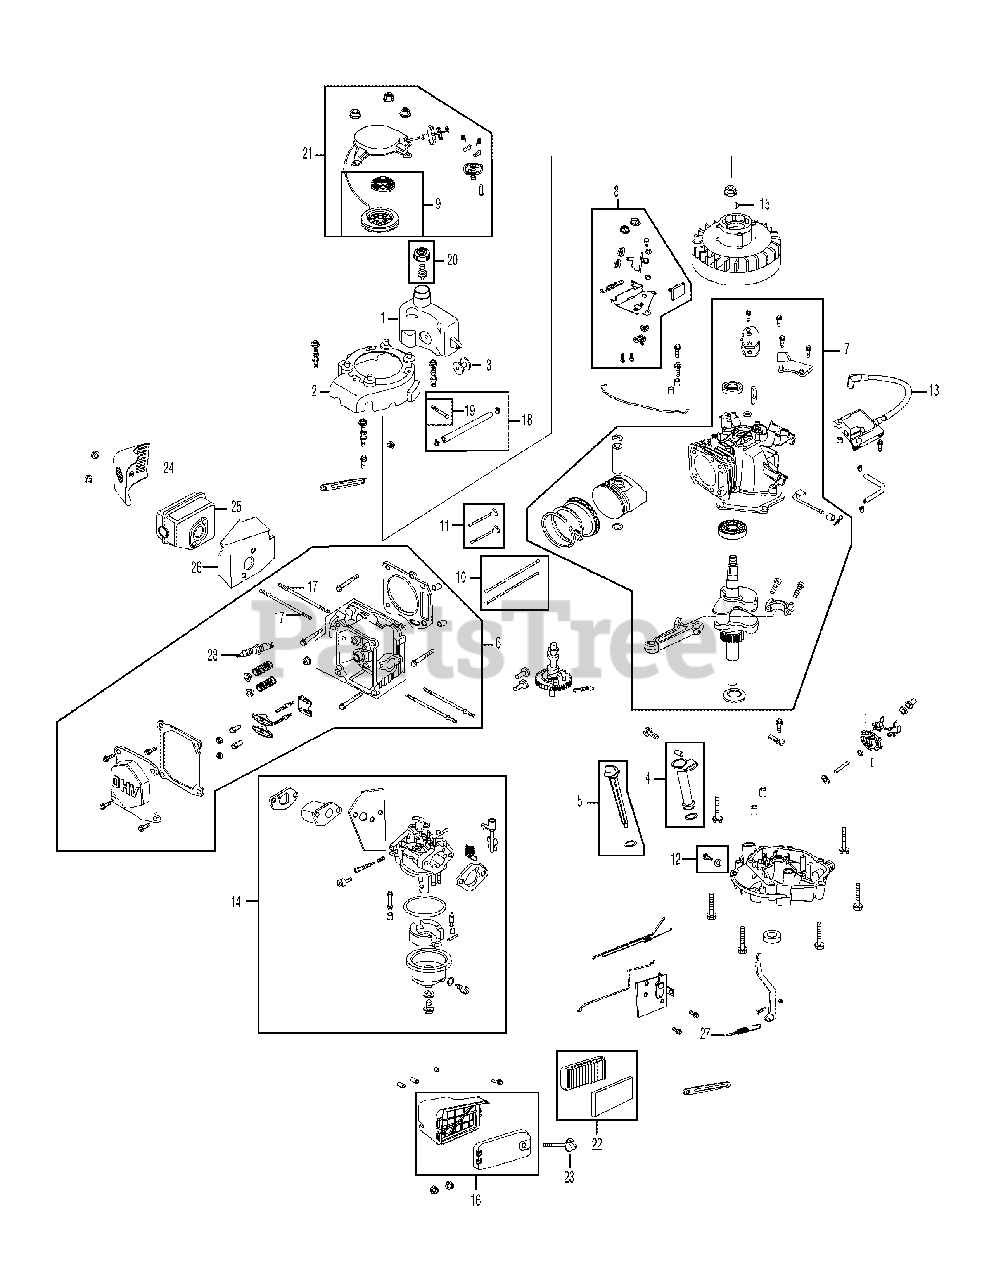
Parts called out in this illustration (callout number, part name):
1	Fuel Tank
2	Flywheel Shroud
3	Rubber Fuel Tank Mounting Washer
4	Oil Filler Tube Assembly
5	Dipstick Assembly
6	Cylinder Head Complete
7	Short Block Assembly
8	Stop Switch and Brake Assembly
9	Recoil Spring and Pulley Assembly
10	Push Rod Kit
11	Valve Kit
12	Oil Drain Plug and Washer Assembly
13	Ignition Coil
14	Carburetor Assembly
15	Flywheel Key
16	Air Cleaner Housing Assembly Complete
17	Muffler Stud Assembly
18	Fuel Line Kit - Inc. hoses, clamps & filter
19	Fuel Filter
20	Fuel Cap Assembly
21	Recoil Starter Assembly
22	Air Cleaner Kit
23	Air Cleaner Thumb Screw
24	Muffler Guard
25	Muffler
26	Muffler Gasket /Heat Shield
27	Governor Return Spring
28	Spark Plug
